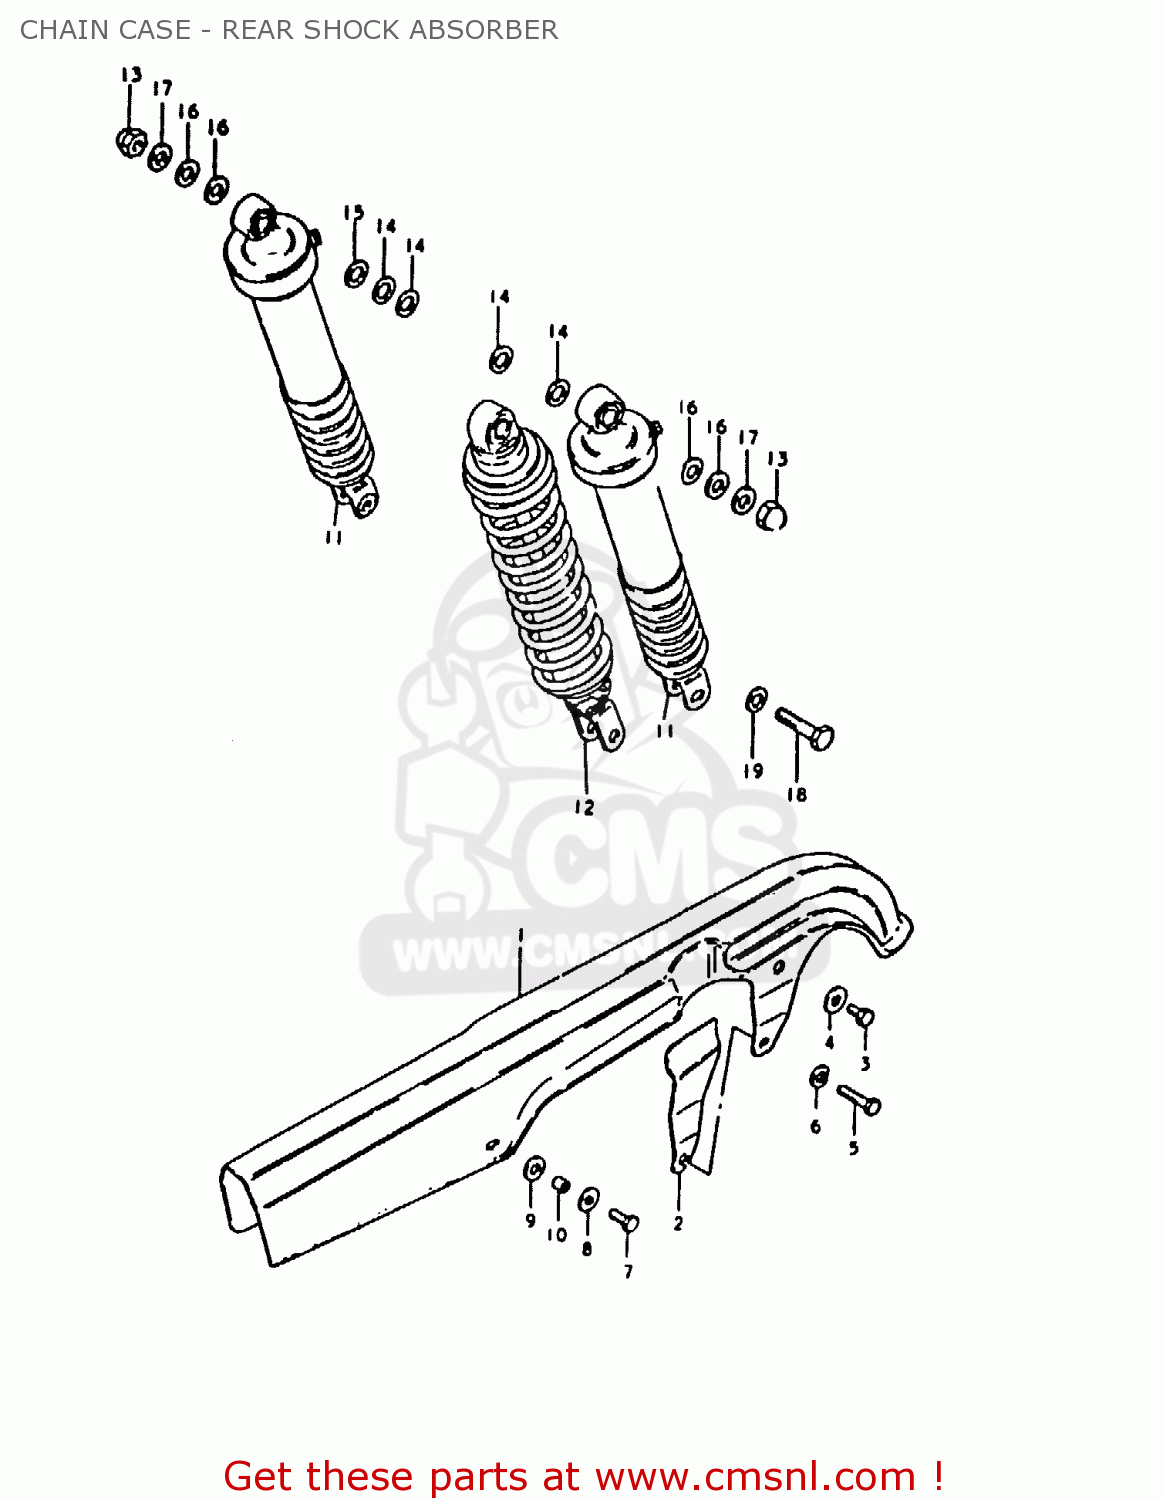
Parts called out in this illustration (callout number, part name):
1	CASE,CHAIN
2	REINFORCEMENT,CHAIN CASE
3	BOLT(6X8)
4	WASHER
5	BOLT
6	LOCK WASHER
7	BOLT
8	WASHER(6.5X18X1)
9	CUSHION
10	SPACER (6.1X8X5.2)
11	ABSORBER ASSEMBLY,REAR SHOCK
12	ABSORBER ASSEMBLY,REAR SHOCK
13	NUT, LOWER LH
14	WASHER
15	WASHER (12.5X24X3.2)
16	WASHER
17	WASHER(10.5X24X3.2)
18	BOLT(10X36)
19	WASHER
